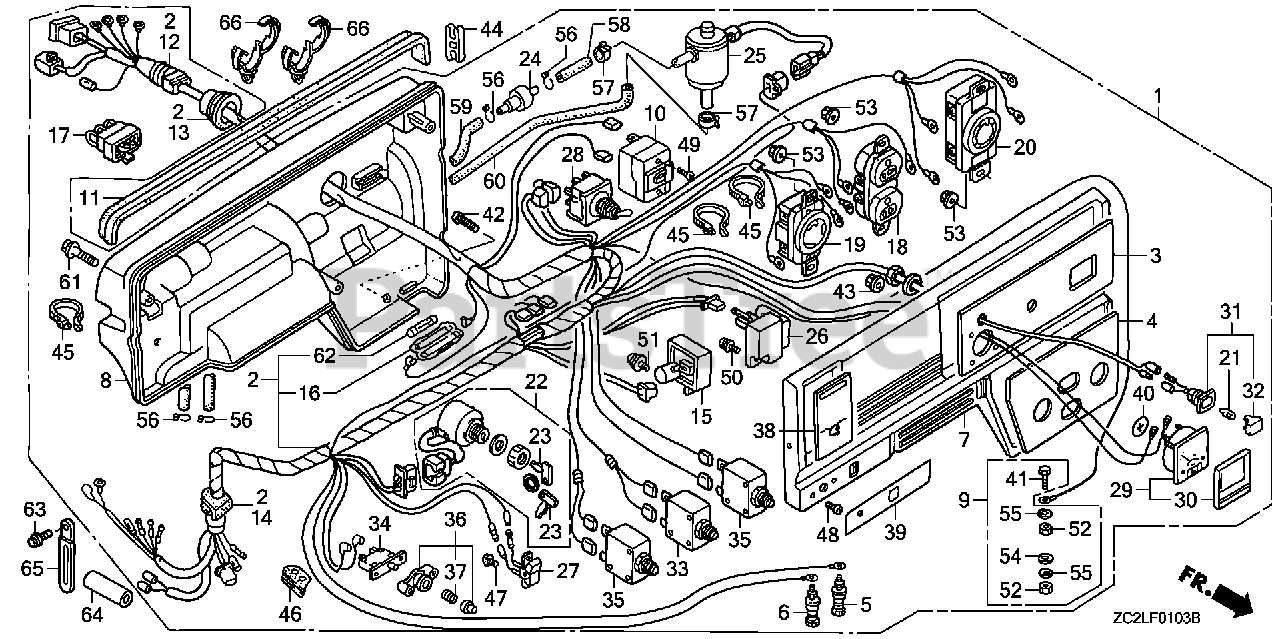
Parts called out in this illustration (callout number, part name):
1	BOX ASSY., CONTROL *R280* (POWER RED)
2	WIRE HARNESS ASSY.
3	MARK, SWITCH PANEL
4	MARK, A.C. OUT
5	TERMINAL, D.C. OUTPUT (+)
6	TERMINAL, D.C. OUTPUT (-)
7	PANEL, CONTROL *R280* (POWER RED)
8	CASE, CONTROL *R280* (POWER RED)
9	TERMINAL SET, GROUND
10	BREAKER, CIRCUIT (19A)
11	RUBBER, CONTROL
12	GROMMET, A.C. WIRE
13	GROMMET, MAIN WIRE
14	GROMMET, SWITCH WIRE
15	DIODE ASSY.
16	CASE, FUSE CONNECTOR (SUMITOMO)
17	CONNECTOR ASSY.
18	RECEPTACLE (20A/125V)
19	RECEPTACLE (30A/125V)
20	RECEPTACLE (30A/125-250V)
21	BULB, WEDGE BASE (12V/2W)
22	SWITCH ASSY., COMBINATION
22	SWITCH ASSY., COMBINATION (HONDALOCK)
23	KEY (HONDALOCK)
24	VALVE, DASHPOT CHECK
25	VALVE ASSY., SOLENOID
26	THROTTLE UNIT, AUTO (SAWAFUJI)
27	SWITCH, AUTO THROTTLE
28	SWITCH ASSY., VOLT CHANGE
29	METER ASSY., VOLT (300V)
30	LENS, METER
31	SOCKET ASSY., LAMP (GREEN)
31	HOLDER, LAMP
32	LENS (GREEN)
33	PROTECTOR, CIRCUIT (20A)
34	PROTECTOR, CIRCUIT (D.C.)
35	PROTECTOR, CIRCUIT (30A)
36	LENS ASSY., PROTECTOR
37	SPRING, COIL
38	MARK, ENGINE SWITCH
39	MARK, D.C. OUT
40	MARK, GROUND
41	BOLT, HEX. (6X28)
42	SCREW, GLOVE BOX
43	NUT, FLANGE (3MM)
44	CLIP, TUBE
45	TIE, CABLE (NATURAL 225X5.0)
46	GROMMET, TUBE
47	SCREW, PAN (3X6)
48	SCREW, PAN (3X12)
49	SCREW, PAN (4X6)
50	SCREW-WASHER (5X12)
51	SCREW-WASHER (4X12)
52	NUT, HEX. (6MM)
53	NUT, FLANGE (4MM)
54	WASHER, PLAIN (6MM)
55	WASHER, SPRING (6MM)
56	CLIP, TUBE (B7)
57	CLAMP, TUBE (D8)
58	BULK HOSE, VACUUM (3.5X8000) (3.5X30)
59	BULK HOSE, VACUUM (3.5X8000) (3.5X530)
60	BULK HOSE, VACUUM (3.5X8000) (3.5X710)
61	BOLT, FLANGE (6X40)
62	FUSE B (10A)
63	BOLT, FLANGE (6X12) (CT200)
64	TUBE, CORD
65	CLIP, WIRE HARNESS
